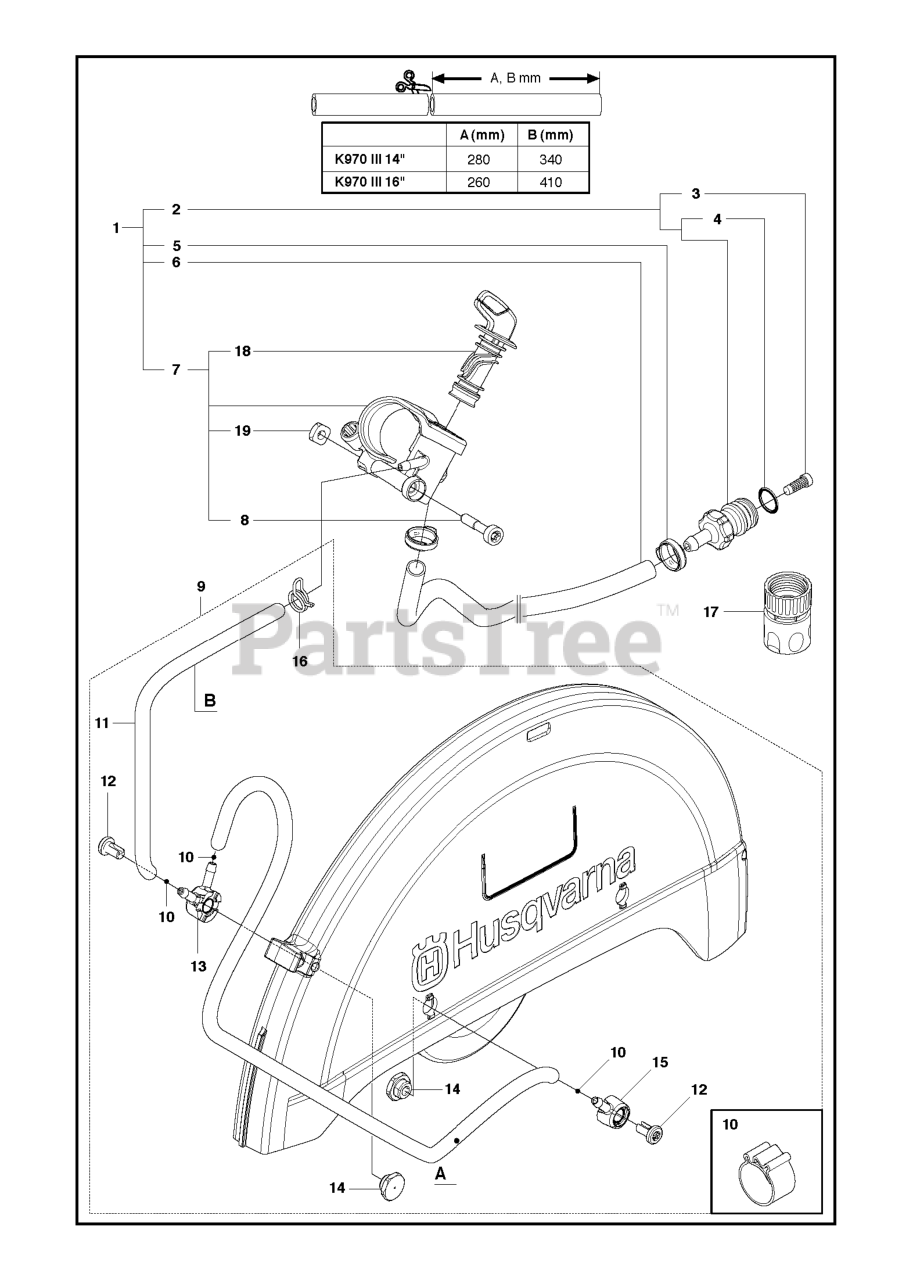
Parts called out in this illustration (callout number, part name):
1	HOSE KIT
2	NIPPLE ASSY WITH O-RING
5	HOSE CLAMP
6	HOSE PVC ARMERAD 6 X 10 (GREY)
7	VALVE ASSY SPARE PART
9	HOSE KIT BLADE GUARD
10	HOSE CLAMP NORMA COBRA 7.5
11	HOSE PVC L800
16	HOSE CLAMP
17	COUPLER, 1/2" HOSE W/STOP ORIG
17	FEMALE QUICK COUPLER
18	LEVER ASSY W O-RINGS SPARE PAR
